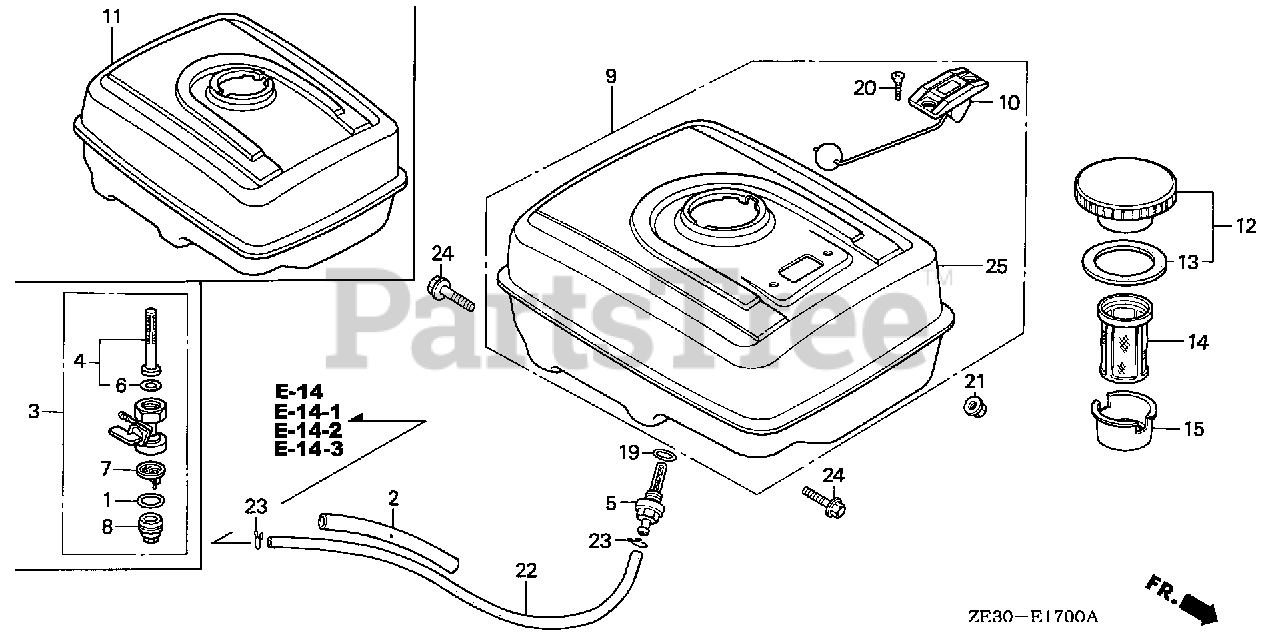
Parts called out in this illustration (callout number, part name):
2	RUBBER, SUPPORTER (107MM)
5	JOINT, FUEL TANK
11	TANK, FUEL *NH31* (MCKINLEY WHITE)
12	CAP, FUEL FILLER (BLACK)
13	GASKET, FUEL FILLER CAP (39X58X3)
14	FILTER, FUEL
15	HOLDER, FUEL FILTER
19	O-RING (13.5X1.5) (ARAI)
19	O-RING (14MM) (NOK)
21	NUT, FLANGE (8MM)
22	BULK HOSE, FUEL (4.5X3000) (4.5X235)
23	CLIP, TUBE (B8)
24	BOLT, FLANGE (8X25)
